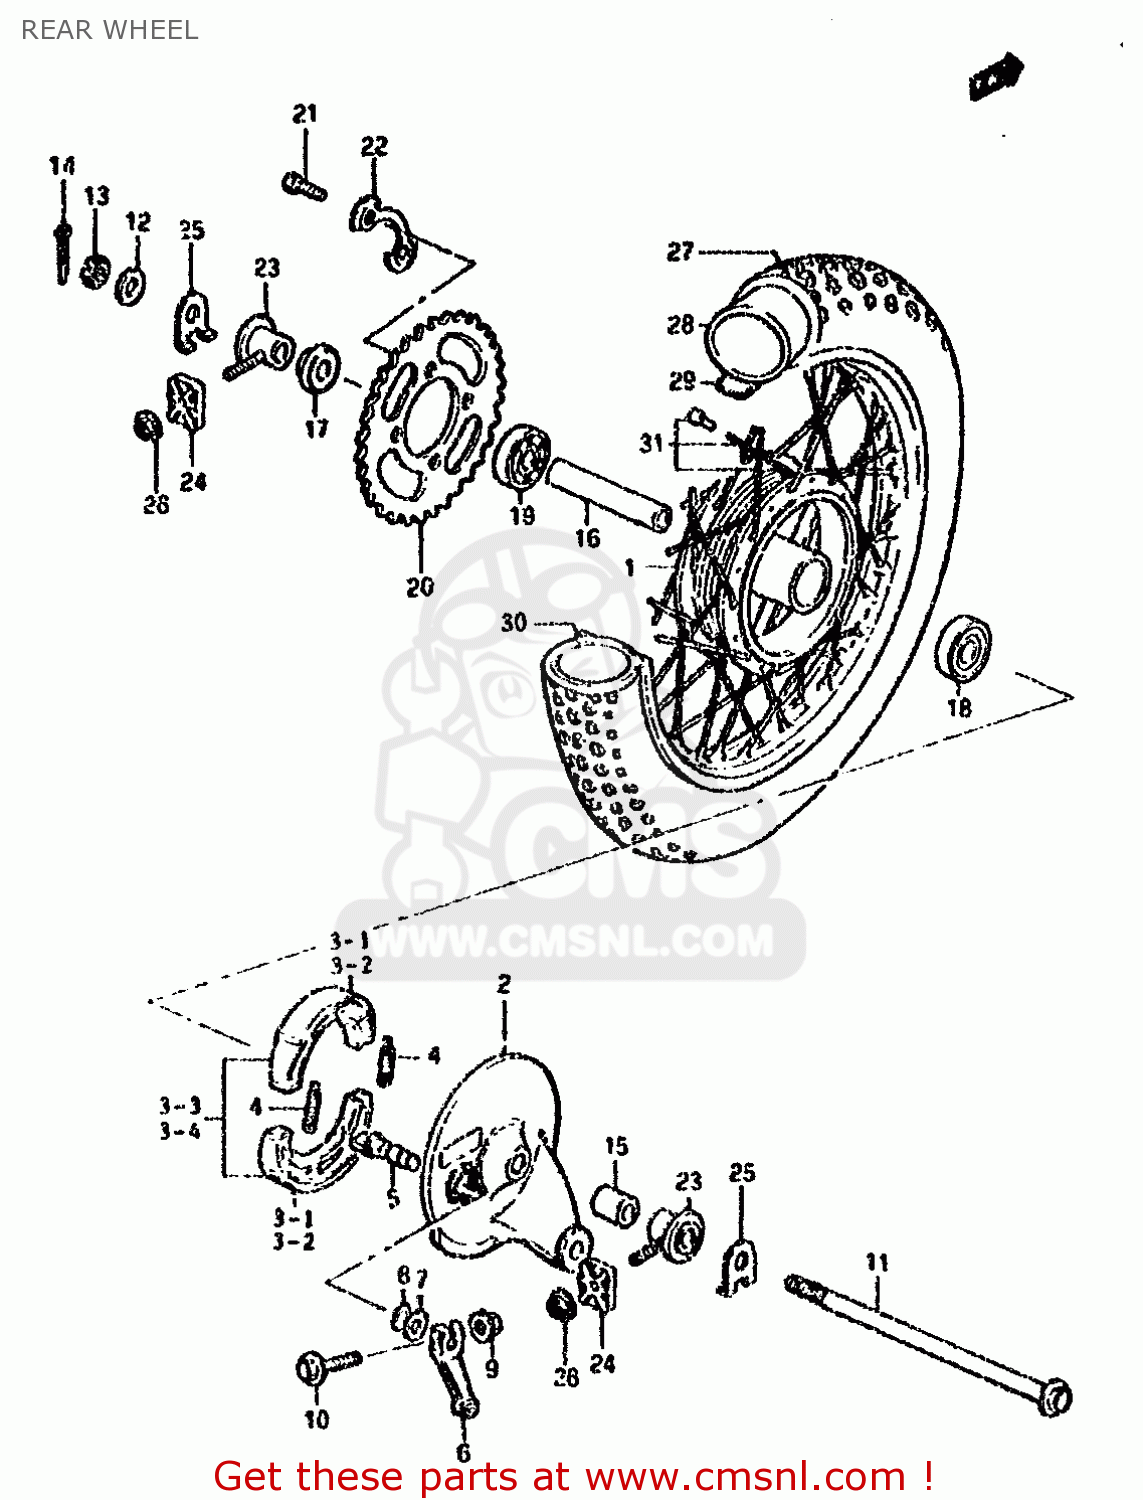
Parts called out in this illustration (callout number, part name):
1	HUB,RR
2	PANEL,RR BRAKE ANCHOR
3	SHOE,BRAKE
4	SPRING(L:35.8)
5	CAM,BRAKE
6	LEVER,RR BRAKE CAM
7	WASHER (14.5X22X1.6)
8	O-RING (D:2.4 ID:13.8)
9	NUT
10	BOLT
11	AXLE,RR
12	WASHER
13	NUT, REAR AXLE
14	COTTER PIN
15	SPACER(12.1X22X22)
16	SPACER(12.6X19X91)
17	SPACER,RR AXLE,L
18	BEARING
19	BEARING
20	SPROCKET,REAR
21	BOLT(8X25)
22	WASHER
23	ADJUSTER,CHAIN
24	PLATE,CHAIN ADJUSTER GUIDE
25	WASHER,CHAIN ADJUSTER
26	NUT
27	TIRE(3.00 12)
28	TUBE,INNER
29	PROTECTOR,INNER TUBE
30	RIM,RR WHEEL(1.60X12)
31	SPOKE ASSY,RR WHEEL
